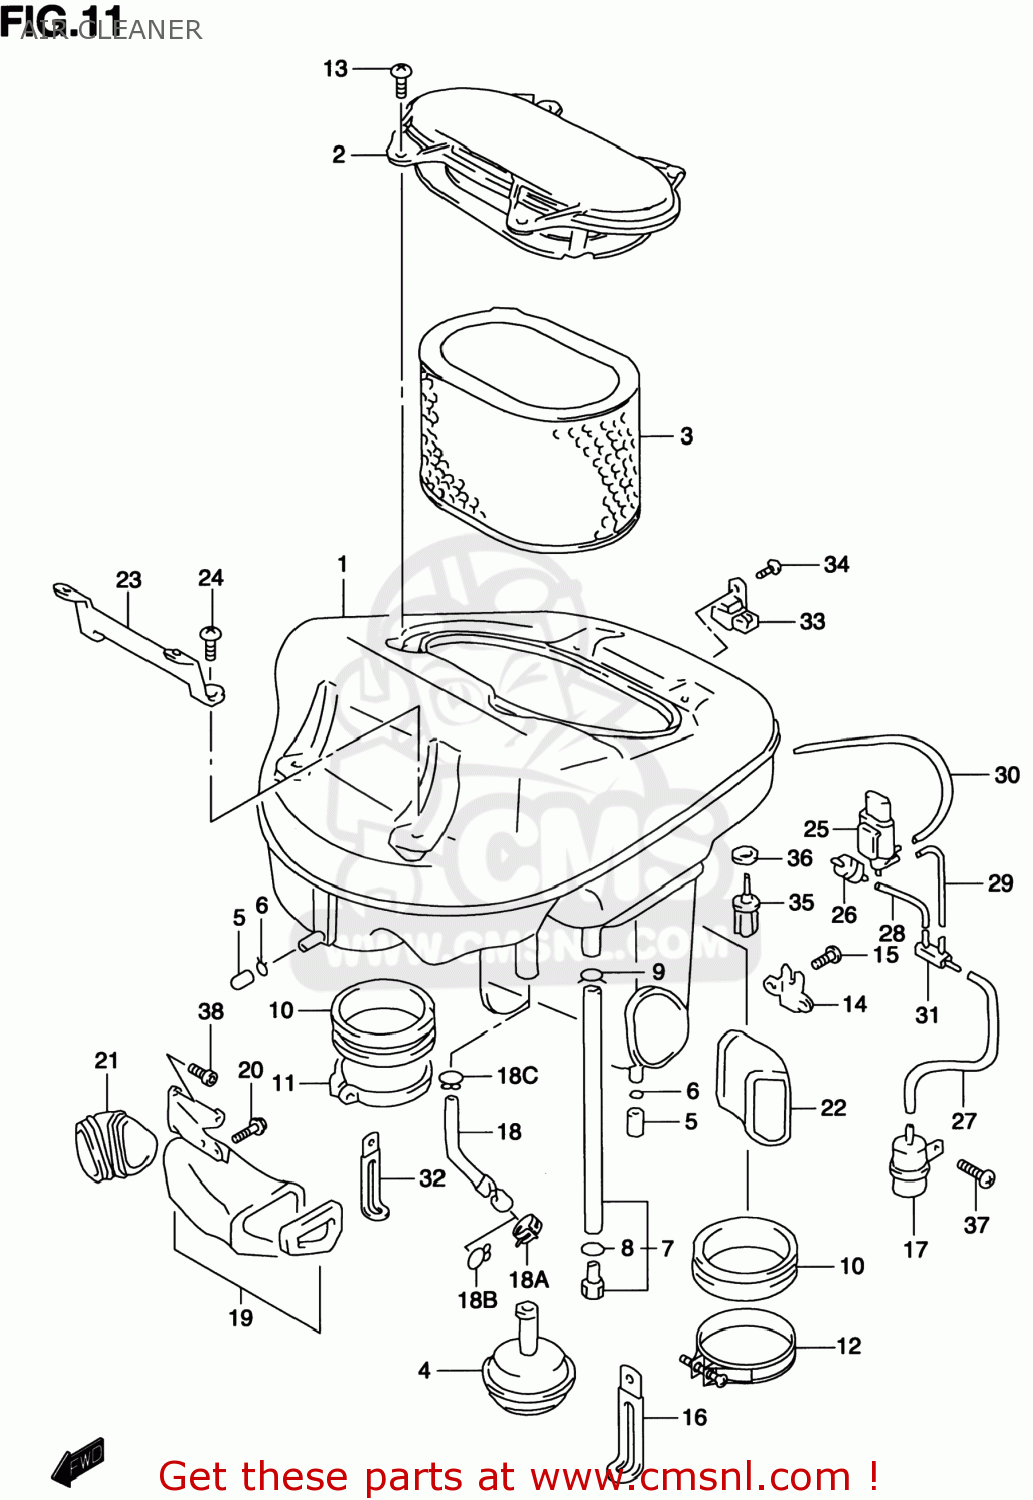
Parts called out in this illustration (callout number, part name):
1	CLEANER ASSY,AIR
2	CAP,AIR CLEANER
3	FILTER,AIR CLEANER
4	DIAPHRAGM,CONT VALVE
5	PLUG
6	CLIP
7	TUBE,DRAIN
8	CLIP
9	CLIP
10	TUBE,OUTLET
11	CLAMP
12	CLAMP
13	SCREW 5X12
14	BRACKET,SOLENOID VALVE
15	SCREW
16	CLAMP(L:65)
17	CHAMBER,VACUUM
18	TUBE,BREATHER
18A	CLAMP
18B	CLIP
18C	CLIP
19	DUCT,AIR CLEANER
20	BOLT
21	BOOT,AIR INLET,R
22	BOOT,AIR INLET,L
23	BRACKET,AIR CLEANER
24	SCREW 6X12
25	VALVE ASSY,3WAY SOLENOID
26	VALVE,CHECK
27	HOSE(4X8X600)
28	HOSE(4X8X600)
29	HOSE(4X8X600)
30	HOSE(4X8X600)
31	JOINT
32	CLAMP(L:80)
33	SENSOR,BOOST
34	SCREW
35	SENSOR,WATER TEMP
36	GASKET(12X17X1) (NAS)
37	SCREW 5X12
38	BOLT
